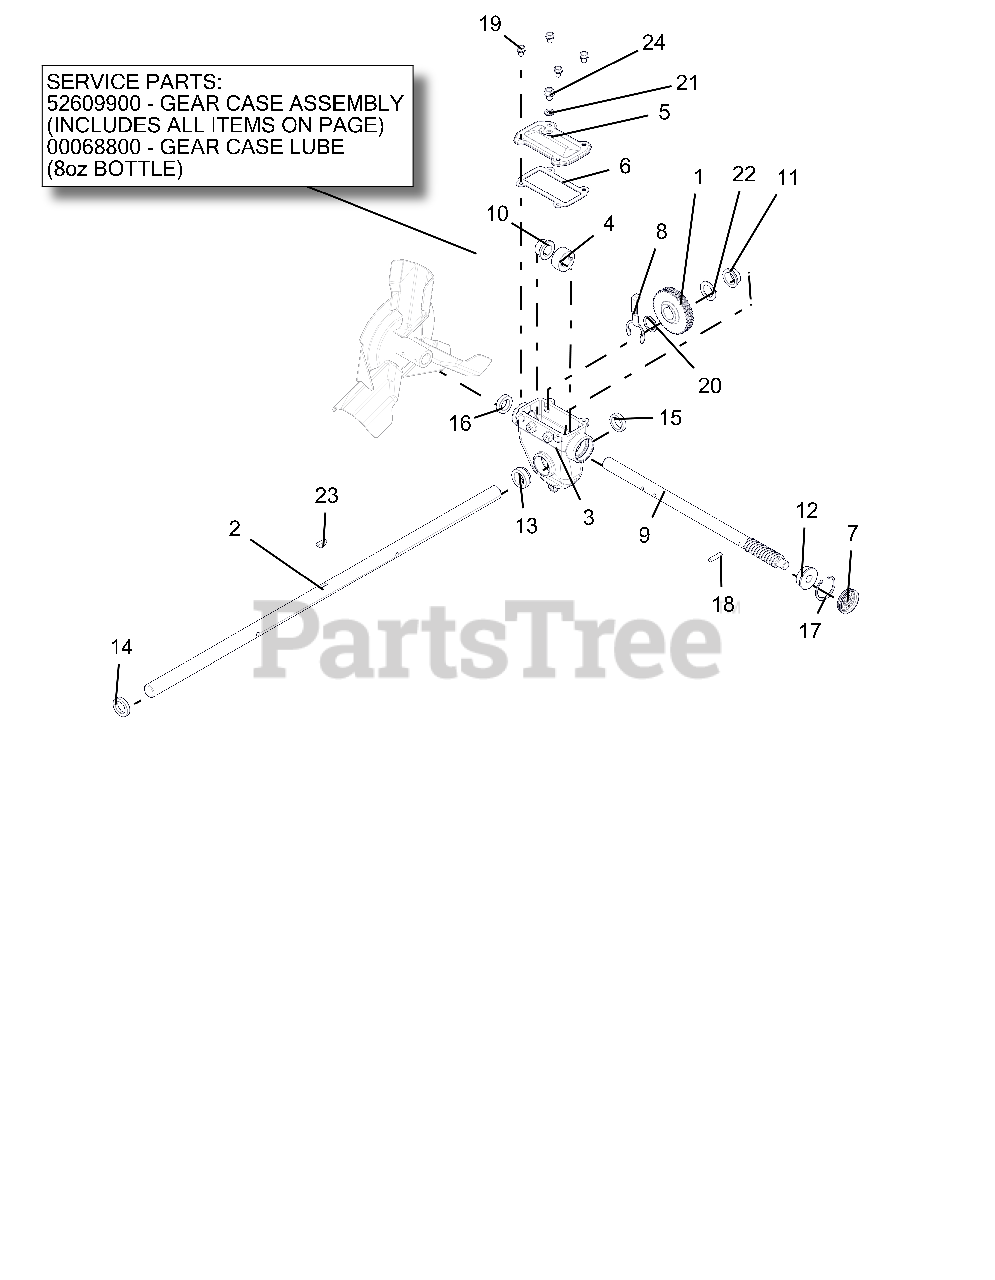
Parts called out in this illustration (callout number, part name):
1	WORM GEAR
2	SHAFT, RAKE-36"
3	GEARCASE, LARGE MACHINED
4	THRUST COLLAR, .875"ID SLIPFIT
5	COVER, TOP - LARGE IRON
6	GASKET, TOP - LARGE GEARCASE
7	COVER, GEAR CASE 1.75"
8	BUSHING RETAINER, LARGE
9	SHAFT, WORM - PRO
10	BSHG-FLG .879X1.128X.75X1.45
11	BSHG-FLG 1.006X1.128X.555X1.45
12	BSHG-FLG .628X1.503X.58X1.725
13	BSHG-FLG LARGE, RIGHT
14	SEAL-OIL .999X1.500X.250 TBC29
15	SEAL-OIL .999X1.375X.312 TBC29
16	SEAL-OIL .873X1.375X.312 TBC29
17	RG-RTNG-INT 1.750X.062
18	PIN-STR .250X1.12 6150
19	BOLT, SEMS .31-18X.50 GR5 YWZC
20	WSHR-FL-STL 1.010X1.250X.068YZ
21	WSHR-BND-SEAL .38X.75X.11 GALV
22	WSHR-FL-STL 1.010X1.505X.062YZ
23	KEY-WDRF .25X.875 HRD #A
24	@SCR-ROLOK .38-16X.50 HWH YWZC
25	GEAR CASE, 36" IRON PRO TOP-LD
26	ARIENS L3 LUBE, 8 OZ BOTTLE
